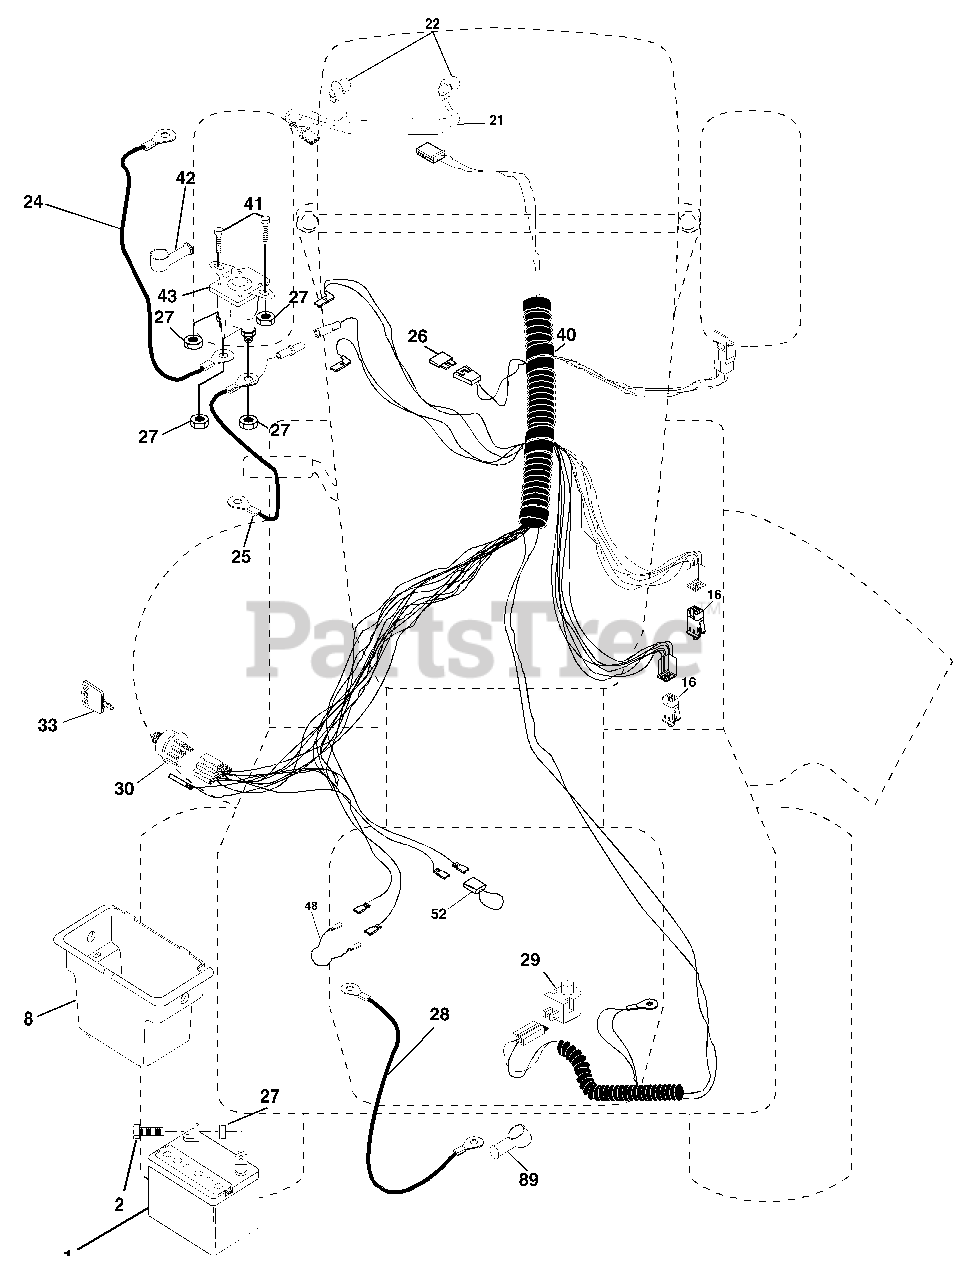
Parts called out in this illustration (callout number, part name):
1	Battery
2	Bolt, Hex Head 1/4-20 unc x 3/4
8	Box Battery Fender
16	Switch, Interlock
21	Harness, Light Socket
22	Bulb, Light
24	Cable, Battery, 6 Gauge, Red, 11"
25	Cable, Battery, 6 Gauge, Red, W/16 Wire
26	Fuse
27	Nut Keps Hex 1/4-20 UNC
28	Cable, Ground, 6 Gauge, Black, 12"
29	Switch, Plunger
30	Switch, Ignition
33	Key, Ignition
40	Harness, Ignition
41	Bolt, Hex Head, Fin. 1/4-20 x 1/2
42	Cover, Terminal, Red
43	Solenoid
48	Adaptor Ammeter Rectangular
52	Protection Wire Loop
89	Cover Terminal Battery
